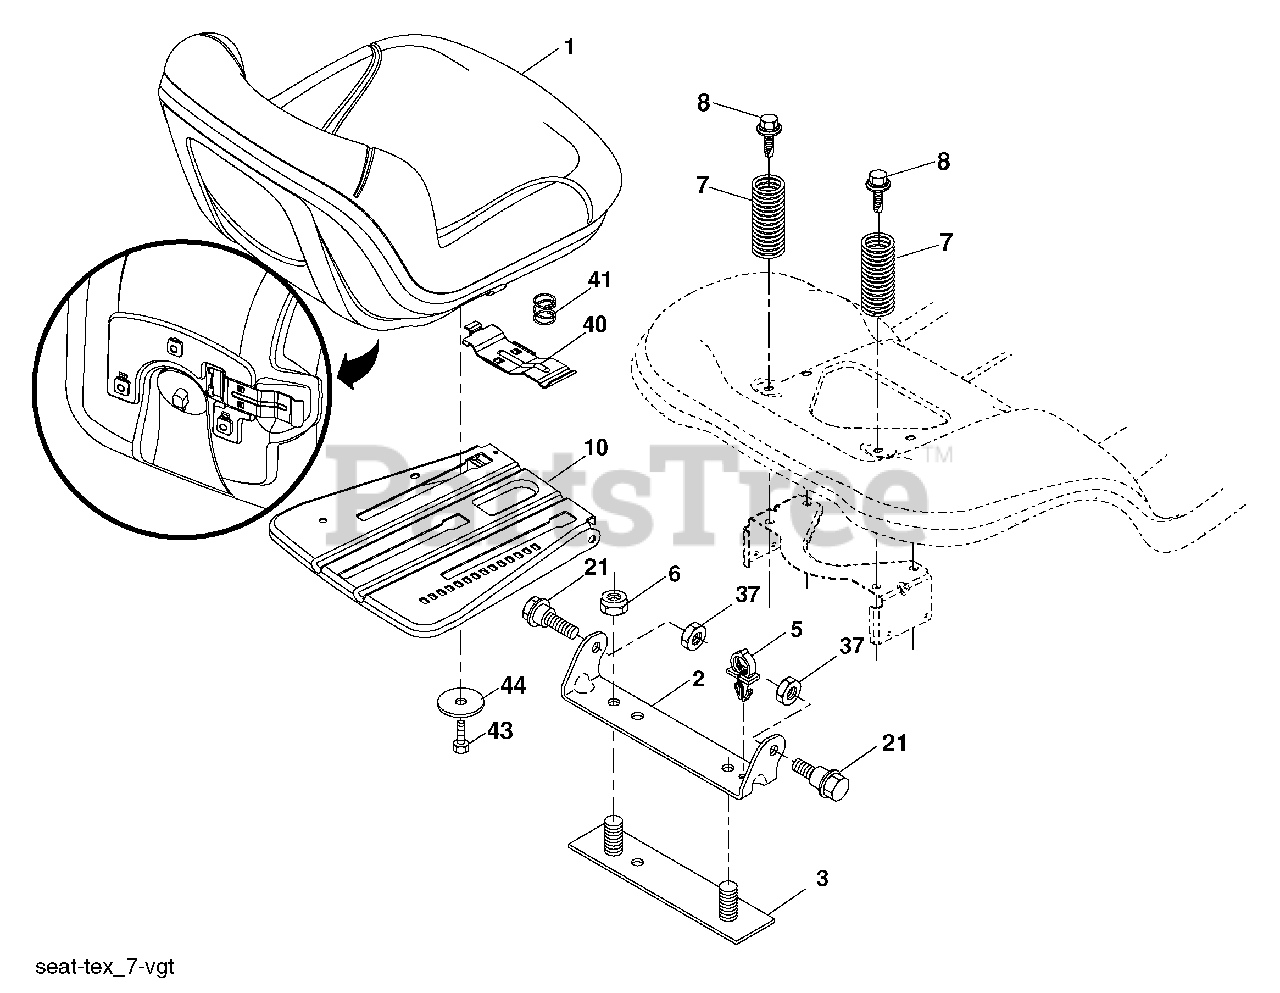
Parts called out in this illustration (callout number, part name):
2	Muffler
9	Keeper Asm. Belt Engine
11	Clutch Electric
12	Pulley Engine
15	Tank Fuel 4.0
18	Cap Asm
20	Control Throttle
21	Screw 10 x 3/4 Single Lead-Hex
22	Control Choke
28	Fuel Line
29	Spark Arrester Kit
31	Clip Push-In Hinged
37	Clamp Hose
41	Washer 1-1/2 OD x 15/32 ID x .250
42	Washer Lock 7/16
45	Nut Keps Hex 1/4-20 unc
62	Shield Heat Muffler
69	Gasket
70	Tube Exhaust LH
71	Tube Exhaust RH
79	Screw Socket Head
81	Tube Drain Oil Easy
82	Plug Drain Oil
84	Screw 3/8-16 x 1-1/4
85	Bolt Hex 7/16-20 x 3.75 Gr. 5
87	Bolt 5/16-18 unc x 1 w/Sems
90	Screw 3/8-16 x 1
